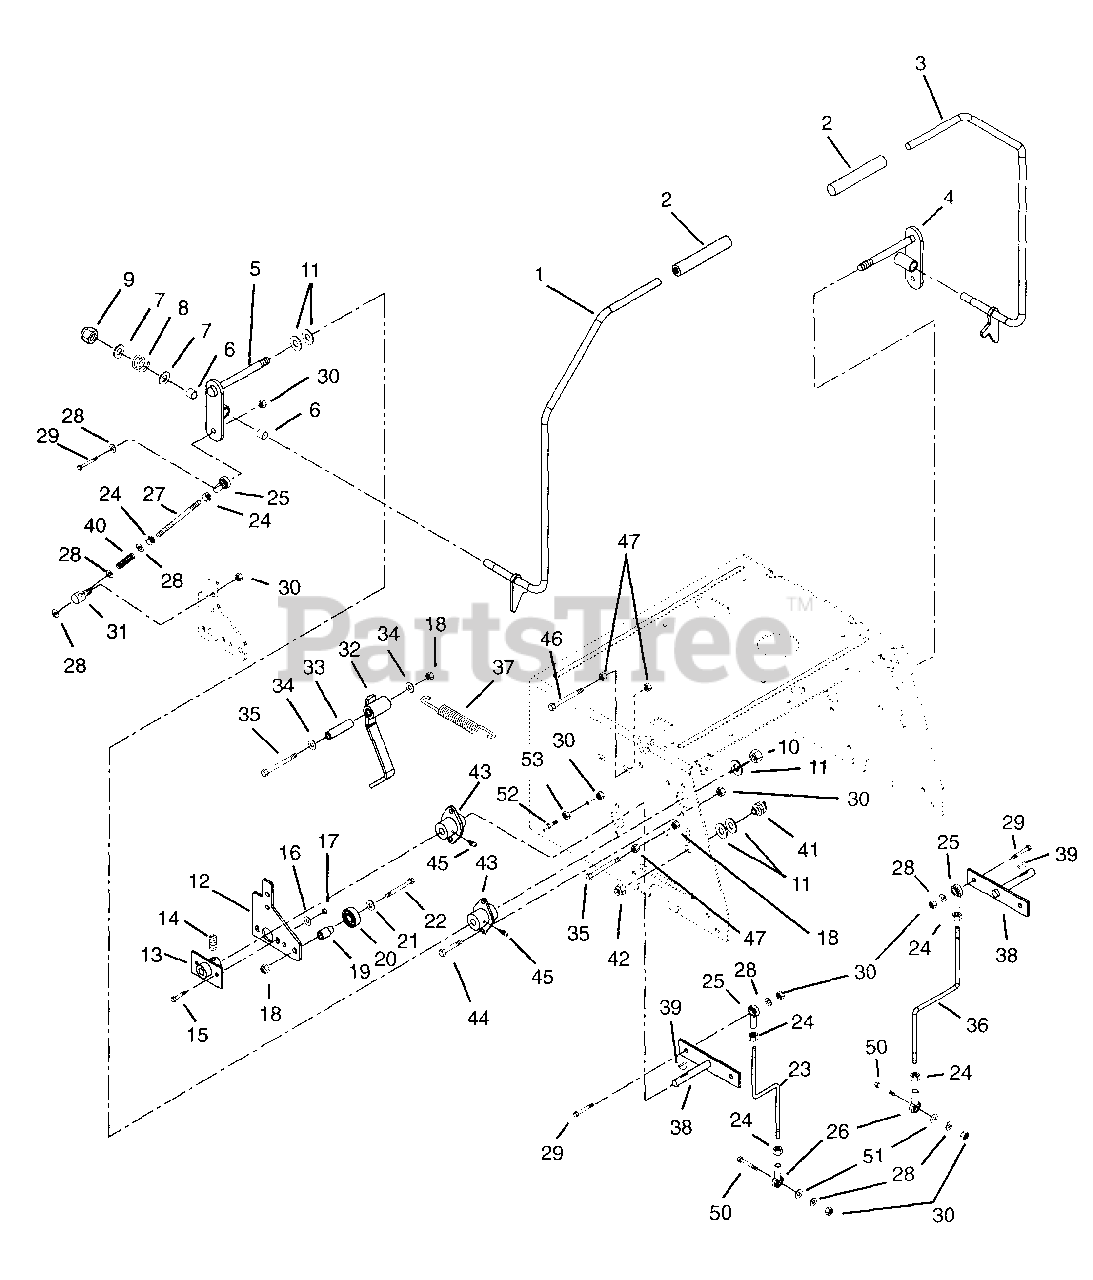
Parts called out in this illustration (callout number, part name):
1	RH STEER-CONTROL LEVER
3	LH STEER-CONTROL LEVER
4	CONTROL WELDMENT LH YWZC
5	CONTROL WELDMENT RH YWZC
6	BUSHING, NYLON .5 X .62 X .5LG
7	WASHER, PLASTIC .12X.53.1.12
8	SPRING, COMPRESSION
9	@NUT-LK-CTR .50-13 YWZC
10	NUT-LK-CTR .50-20 YWZC
11	@WSHR-FL-STL.563X1.38X.109YWZC
12	ARM, SPEED CONTROL
13	ARM, SPEED CONTROL
14	SCR-SET .25-20X.38 SKHCUP OH
15	@BLT-HEX .25-20X.75 GR5 YWZC
16	@WSHR-FL-STL.281X.62X.065 YWZC
17	@NUT-LK-CTR .25-20 YWZC
18	NUT-LK-CTR .375-16 YWZC
19	HUB, BRG. MOUNT
20	BRG-BALL .500X1.375X.437
21	@WSHR-FL-STL.406X.812X.065 YWZ
22	@BLT-HEX .38-16X2.00 GR5 YWZC
23	ROD, TRANSAXLE RH
24	NUT-JAM .31-24 YWZC
25	ROD END, 5/16 RH - FEMALE
26	ROD END, 5\16 LH - FEMALE
28	@WSHR-FL-STL.344X.688X.065YWZC
29	@BLT-HEX .31-18X1.00 GR5 YWZC
30	@NUT-LK-CTR .31-18 YWZC
31	PIVOT, ROD
32	WLDM'T, NEUTRAL DETENT
33	BUSH.,S.385X.610X1.80 ST
34	@WSHR-FL-STL.406X.812X.065 YWZ
35	@BLT-HEX .38-16X2.75 GR5 YWZC
36	ROD, TRANSAXLE LH
37	SG-TENS .085X.60X5.13 WLD8.3
38	PUMP CONTROL WELDMENT RH
39	KEY-WDRF .125X.75
40	SG, VARIBLE RATE
41	SWITCH, NEUTRAL START N.O.
42	NUT-STAMPED .56-18
43	BUSHING, FLANGED
44	@BLT-HEX .31-18X.75 GR5 YWZC
45	FTG-LUBE .25-28X.256 YWZC
46	BLT-HEX .38-16X3.00
47	@NUT-HEX .38-16 YWZC
48	TRANSAXLE ROD ASSEMBLY, RH
49	TRANSAXLE ROD ASSEMBLY, LH
50	@BLT-HEX .31-18X1.25 GR5 YWZC
51	WSHR-FL-STL .344X1.375X.075YWZ
52	@BLT-HEX .31-18X1.75 GR5 YWZC
53	@NUT-HEX .31-18 YWZC
